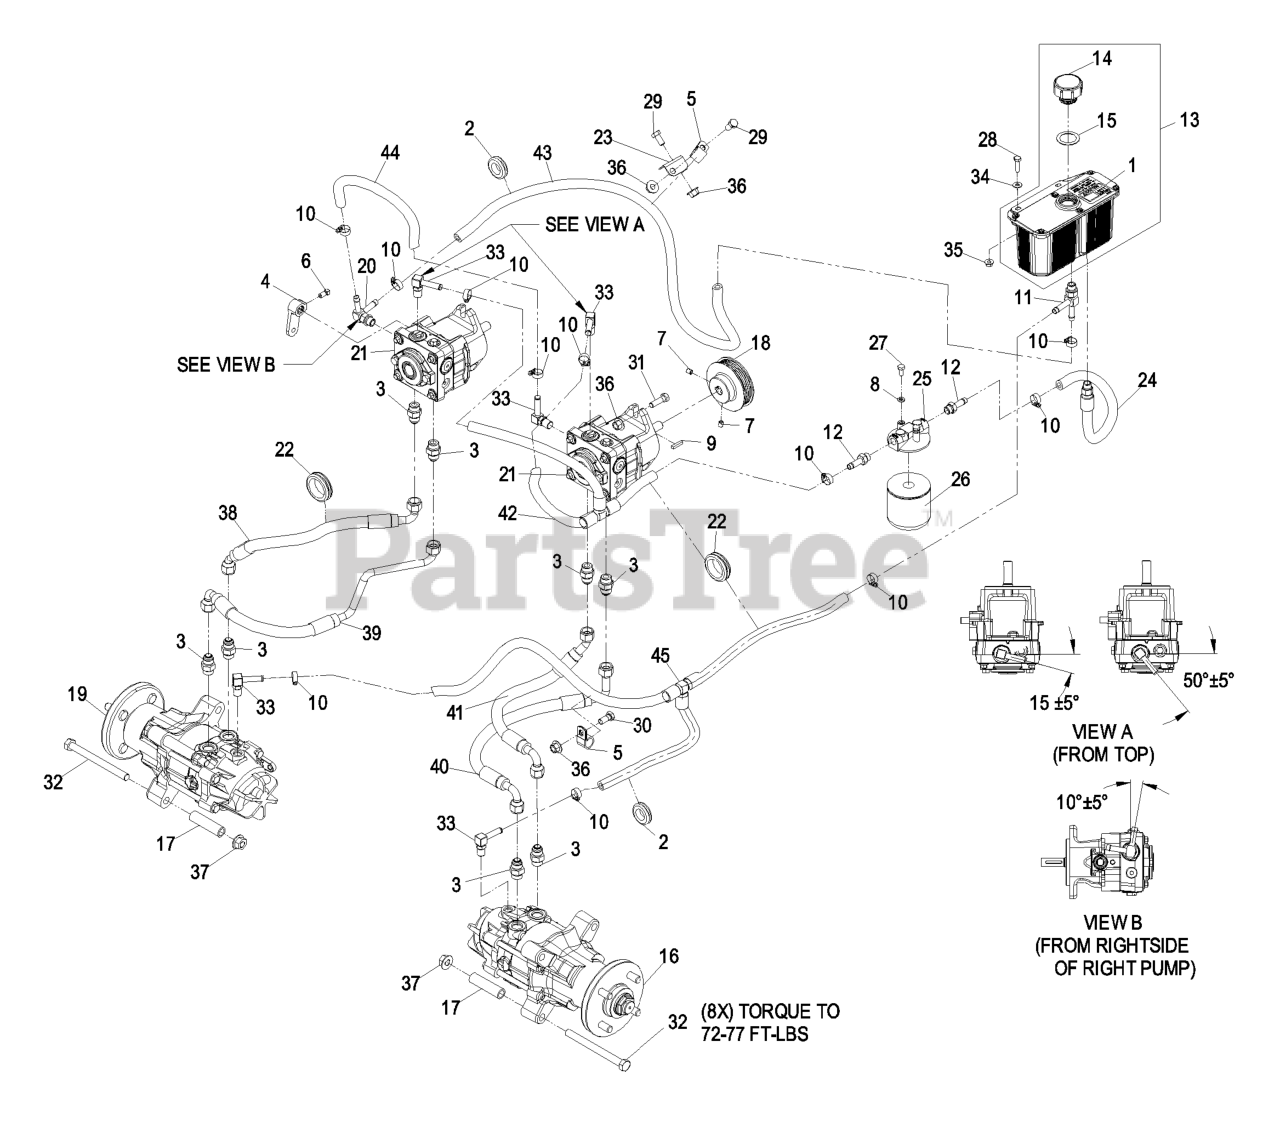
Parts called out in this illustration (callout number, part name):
2	GROMMET
3	FITTING-STRAIGHT
4	ARM-CONTROL, PUMP
5	CLIP-LOOM
6	SCREW-SET
7	SCREW-SET
8	WASHER-LOCK
10	CLAMP-HOSE
11	ADAPTER-RUN, TEE
12	ADAPTER-STRAIGHT
13	HYD RESERVOIR ASM
14	Cap-Reservoir, HYD
15	GASKET-CAP
16	MOTOR,PRM18-LH
19	MOTOR,PRM18-RH
20	ADAPTER-TEE
22	GROMMET
23	BRACKET-CLAMP
25	HEAD-FILTER
26	Element, Filter 25 Micron
27	SCREW-HH
28	SCREW-HH
29	SCREW-HH
30	SCREW-HH
31	SCREW-HH
32	SCREW-HH
33	FITTING-HYD, 90 DEG
34	WASHER-FLAT
36	NUT-FLANGE
37	NUT-HHF
38	ASM,HYD HOSE
39	HOSE,HYD ASM
40	ASM,HYD HOSE
41	ASM,HYD HOSE
42	ASM,HYD HOSE
43	HOSE-HYD
44	HOSE-HYD
45	ASM,HYDRAULIC HOSE
